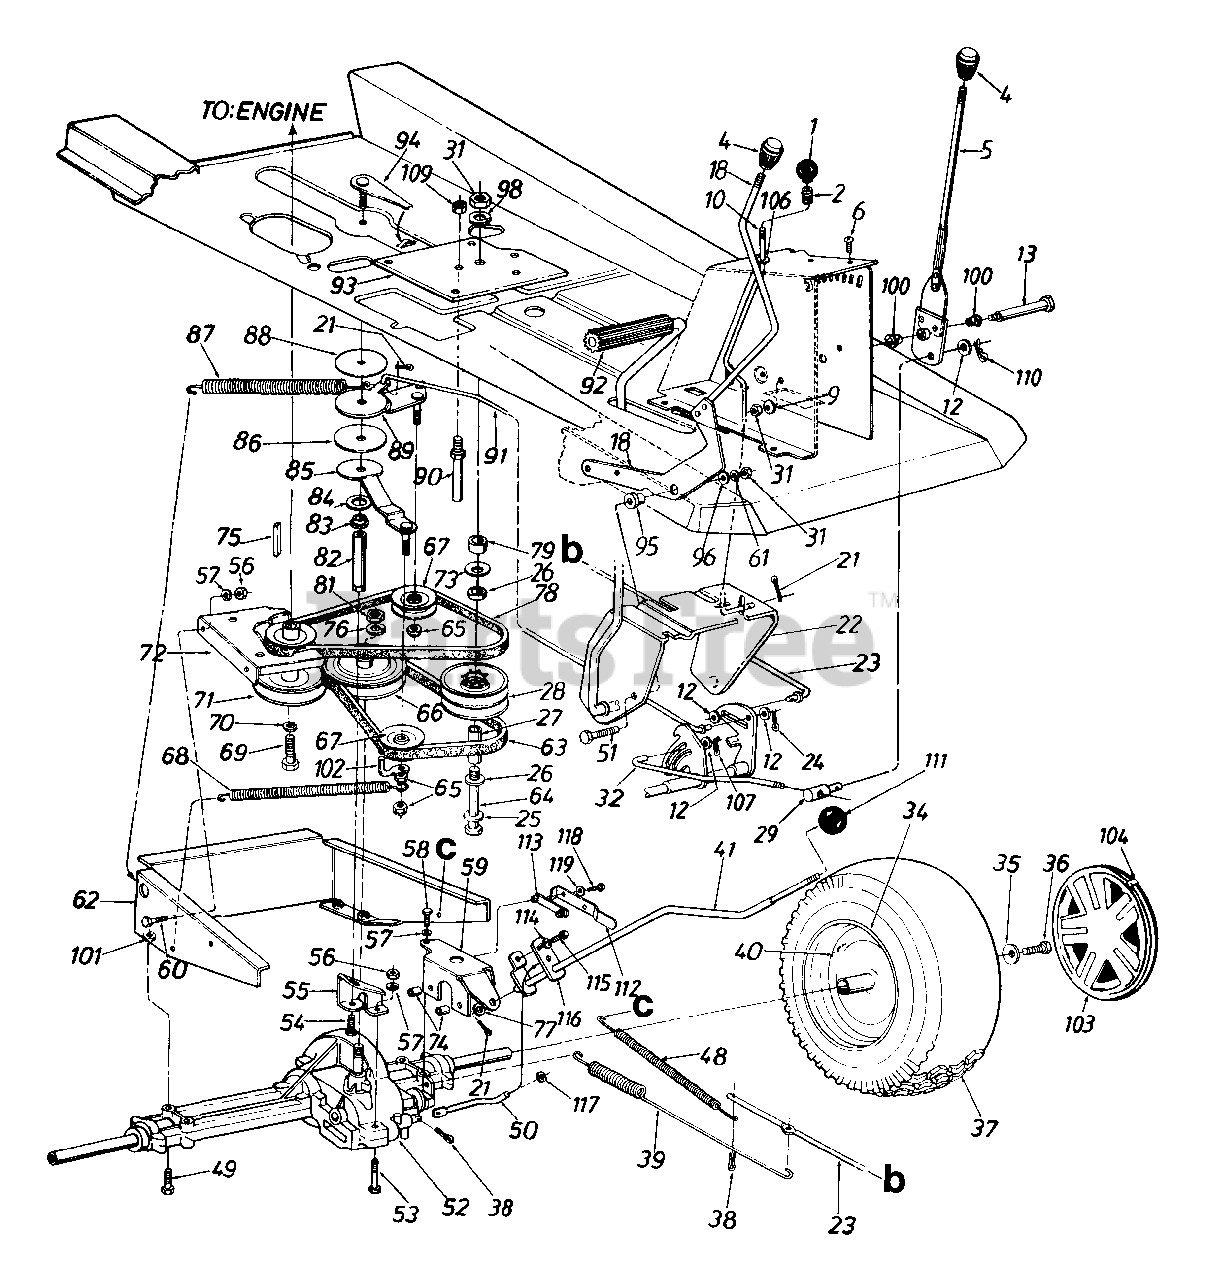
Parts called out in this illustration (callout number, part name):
1	Ball Knob 1/4-20 Thd.
2	Compression Spring
4	Shift Knob
5	Shifter Ass'y. w/Handle
6	Pan Hd. Tap Scr. #12 x .5" Lg.
9	Bell-Wash. .4" I.D.
10	Parking Brake Rod
12	FI-Wash. .34" I.D. x .68" O.D.
13	Shld. Bolt .498" Dia. x 4.75" Lg.
24	Cotter Pin 1/8" Dia. x 1.0"
25	FI-Wash. .406" I.D. x 1.125"
26	Thrust Brg. .56" I.D.
27	Spacer Sleeve 2.71" Lg.
28	Variable Speed Pulley Ass'y.
29	Ferrule
31	Hex Nut 3/8-16 Thd.
32	Speed Control Link
35	Bell-Wash. .345" I.D. x .88"
36	Hex L-Bolt 5/16-24 x .75" Lg.
38	Cotter Pin 1/8" Dia. x 1.25"
39	Extension Spring 17" Lg.
40	Air Valve
41	Shift Lever Ass'y.
48	Extension Spring 8.25" Lg.
49	Hex Bolt 5/16-18 x 2.5" Lg.
50	Shift Rod
51	Hex Bolt 3/8-16 x 1.25" Lg.
52	Transaxle
53	Hex Bolt 1/4-20 x 1.75" Lg.
54	Hex Bolt 3/8-24 x .75" Lg.
57	L-Wash. 1/4" I.D.
58	Self-Tap Mach. Scr. 1/4-20 x 1.37" Lg.
59	Shift Lever Support Brkt.
60	Hex Bolt 1/4-20 x 1.0" Lg.
61	L-Wash. 3/8" I.D.
64	Hex Bolt 3/8-16 x 4.5" Lg.
65	Hex L-Nut 3/8-24 Thd.
66	"V"-Pulley
67	"V"-Belt Idler
68	Ext. Spring 6.37" Lg.
69	Hex Bolt 7/16-20 x 1.0" Lg.
70	L-Wash 7/16" I.D.
71	Engine Pulley
72	Upper Belt Guard
73	Bell-Wash. .40" I.D. x 1.12" O.D.
74	Spacer .256" I.D. x .5" O.D.
75	Sq. Key 1/4" x 2.0" Lg.
76	Bell-Wash. .567" I.D. x 1.125"
77	Fl-Wash .469" I.D. x .88" O.D.
78	"V"-Belt
79	Spacer .38" I.D. x 1.0" O.D.
81	Hex Jam Nut 9/16-18 Thd.
82	Torque Rod
83	Flange Bearing .378" I.D.
84	FI-Wash. .64" I.D. x 1.24" O.D.
85	Idler Bracket Ass'y.
86	Thrust Washer .635" I.D.
87	Extension Spring 7.58" Lg
88	Thrust Wash. .385" I.D.
89	Idler Bracket Ass'y.
90	Belt Guard Pin 3/8-16 x 2.75" Lg.
91	Clutch Rod
92	Foot Pad
96	Fl-Wash. .406" I.D. x 1.25" O.D.
98	L-Wash. 3/8" I.D. (Heavy Duty)
100	Flanged Nyliner Brg.
101	Hex Sems Nut 5/16-18 Thd.
102	Belt Guard
104	Spring Clip
106	Fl-Wash. .281" I.D. x .5" O.D.
107	Intern. Cotter Pin 1-1/8" Lg.
109	Hex Top L-Jam Nut 3/8-16 Thd.
110	Internal Cotter Pin 3/8" Dia.
111	Ball Knob
112	Spring Switch
113	Insulator Nut Plate
114	Bell-Wash. .265" I.D. x.75" O.D.
115	Hex Bolt 1/4-20 x .5" Lg.
116	Shift Lever Adjusting Link
117	Retaining Ring
118	Hex Wash. Hd. Scr. #8 x .5" Lg.
119	Plastic Washer
